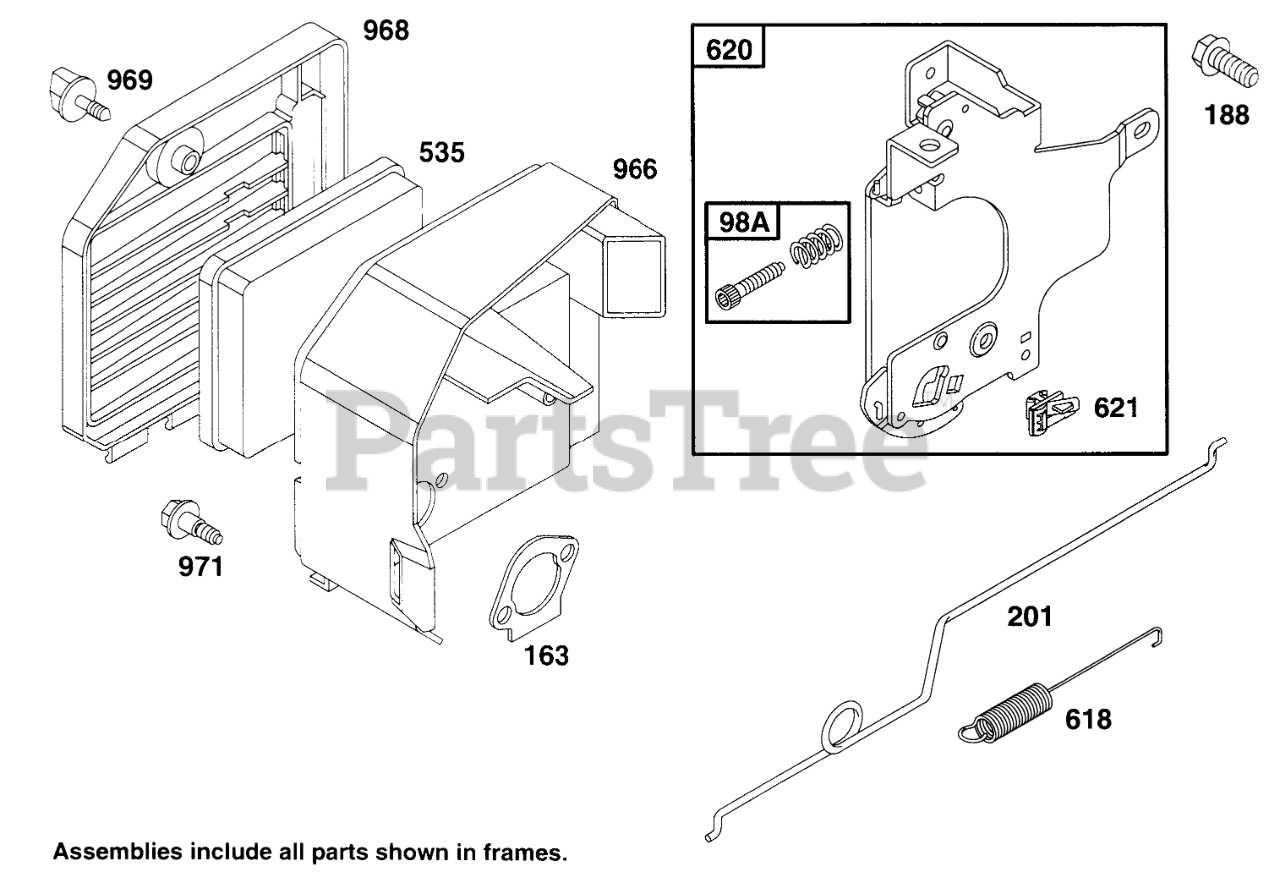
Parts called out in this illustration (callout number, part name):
98A	SPEED ADJUST. SCREW ASM
163	AIR CLEANER GASKET
188	SCREW - HEX HEAD
201	GOVERNOR LINK
535	FILTER ELEMENT
618	RETURN SPRING
620	CARBURETOR BRACKET
621	STOP SWITCH
966	AIR CLEANER BASE
968	AIR CLEANER COVER
969	AIR CLEANER SCREW
971	AIR CLEANER SCREW
